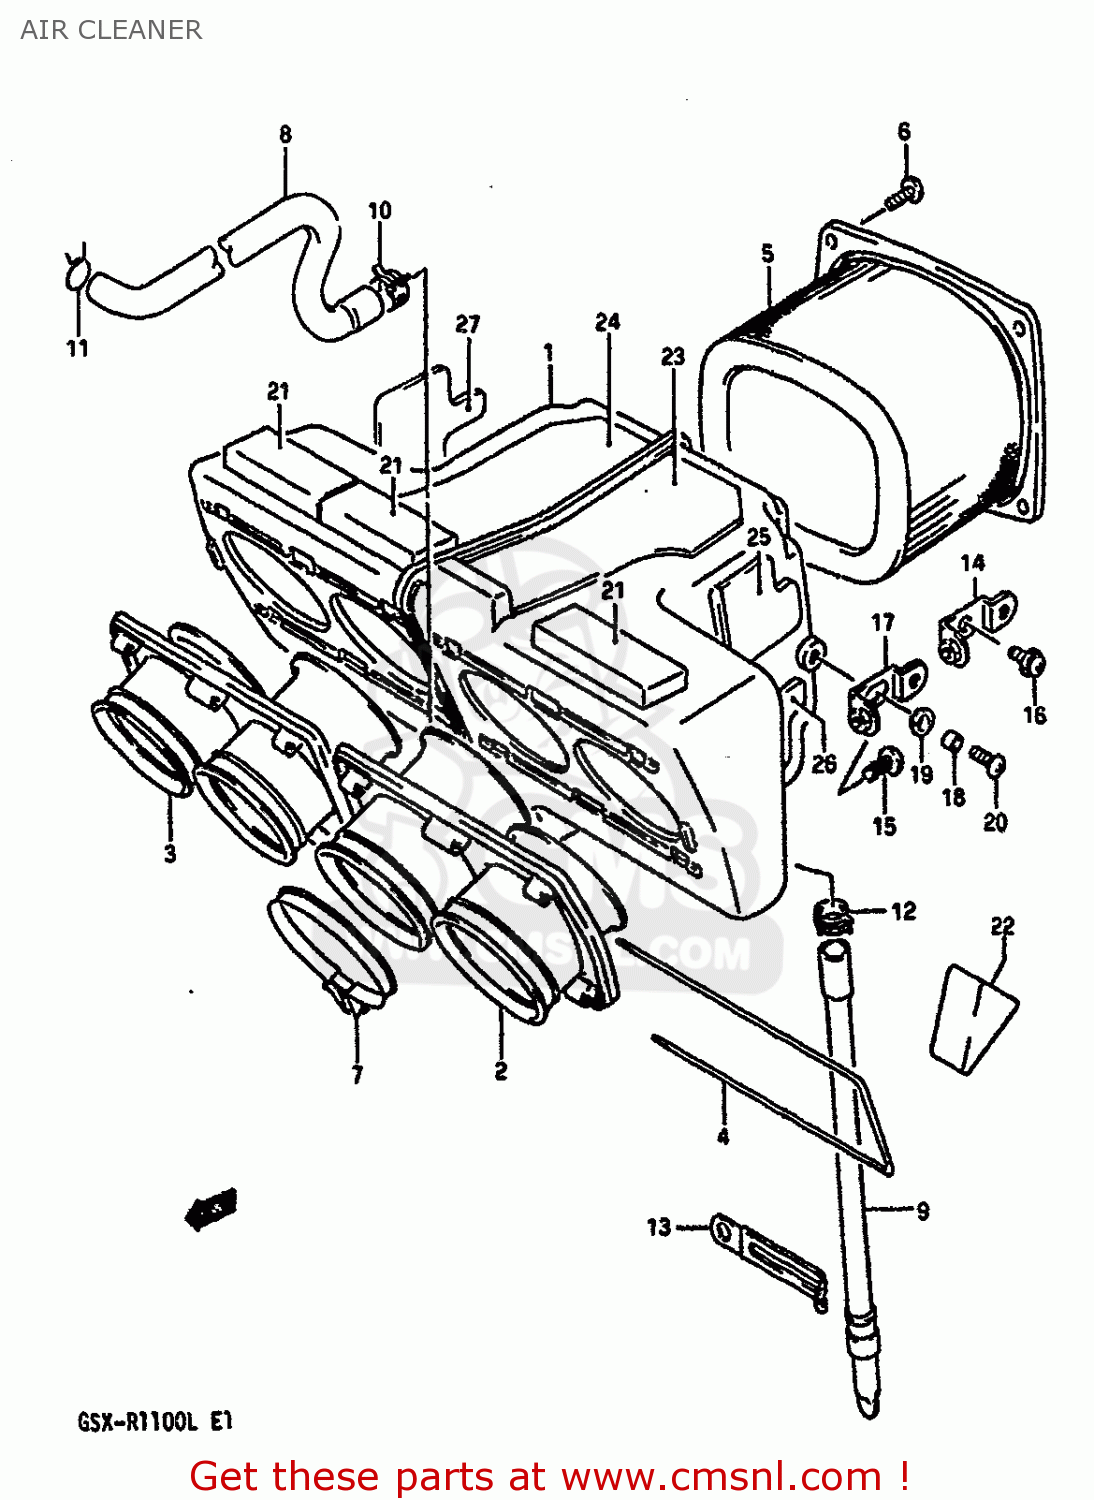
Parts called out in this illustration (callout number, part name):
1	CASE,AIR CLEANER
2	TUBE,AIR CLEANER OUTLET LH
3	TUBE,OUTLET,R
4	SHAFT,OUTLET TUBE
5	FILTER ASSY,AIR
6	SCREW
7	CLAMP
8	TUBE,BREATHER
9	DRAIN TUBE
10	CLIP
11	CLIP
12	CLIP
13	CLAMP
14	BRACKET COMP,AIR CLEANER
15	SCREW
16	SCREW
17	BRACKET,AIR CLEANER CASE
18	SPACER
19	WASHER
20	SCREW
21	CUSHION,AIR CLEANER CASE
22	CUSHION,AIR VENT HOSE
23	SHEET,AIR CLEANER NO.1
24	SHEET,AIR CLEANER NO.2
25	SHEET,AIR CLEANER NO.3
26	SHEET,AIR CLEANER NO.4
27	SHEET,AIR CLEANER NO.5
